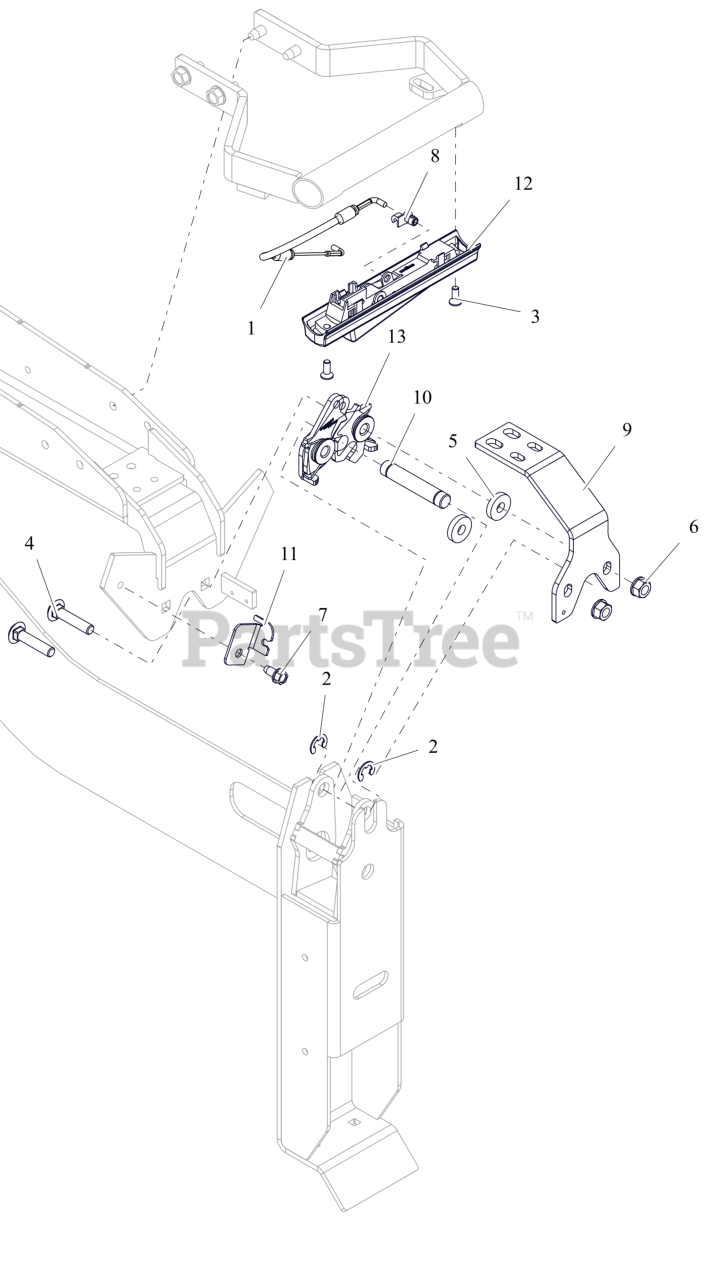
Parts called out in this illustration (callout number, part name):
1	CABLE, HOOD RELEASE
2	RG-RTNG-EXT .438X.035
3	SCR, FLCSKH M5-0.8X14 GR10.9 ROHS
4	BLT,RHSN .31-18X1.50 G5 ZCC
5	WSHR, FLT .328X.870X.179 ZCC
6	NUT,LK-CTR-FLG .31-18 GF ZCC
7	SCR-TAP .25-20X.50 HWH ZCC
8	CLIP, RETAINER
9	BRKT, LATCH MTG
10	ROD, LATCHING
11	RETAINER, CABLE (BLACK)
12	HANDLE, SQUEEZE ACTUATOR
13	LATCH, PUSH TO CLOSE
